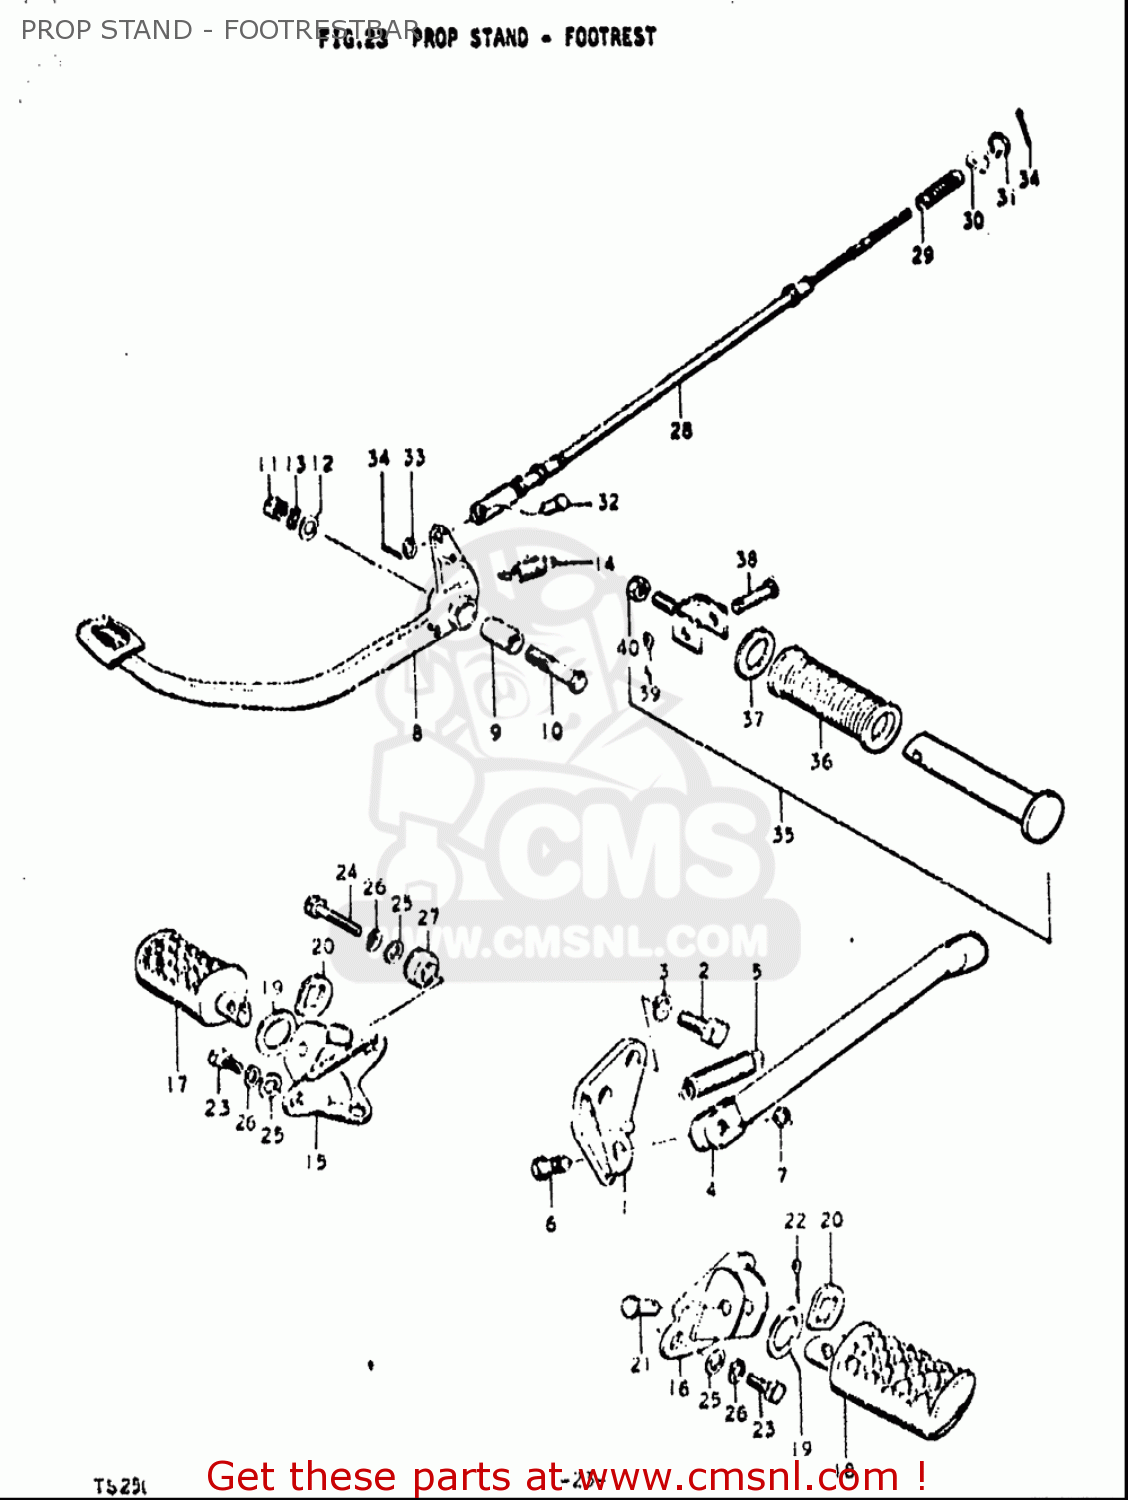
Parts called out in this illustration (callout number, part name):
2	BOLT
3	WASHER,LOCK
5	SPRING
6	BOLT(10X30)
7	NUT
9	SPACER(10.5X16X30)
11	NUT
12	WASHER
13	WASHER,LOCK
19	WASHER(22.5X38X1)
20	WASHER
21	PIN
22	PIN
23	BOLT(8X14)
24	BOLT
25	WASHER
26	WASHER,LOCK
28	CABLE ASSY,RR BRAKE
29	SEAL,DUST
30	PIN(13X18)
31	NUT
32	PIN(L:17.5)
33	WASHER
34	PIN
35	FOOTREST ASSEMBLY,REAR
36	RUBBER,PILLION FOOTREST
37	WASHER(19.5X32X2)
38	PIN
39	PIN
40	NUT
